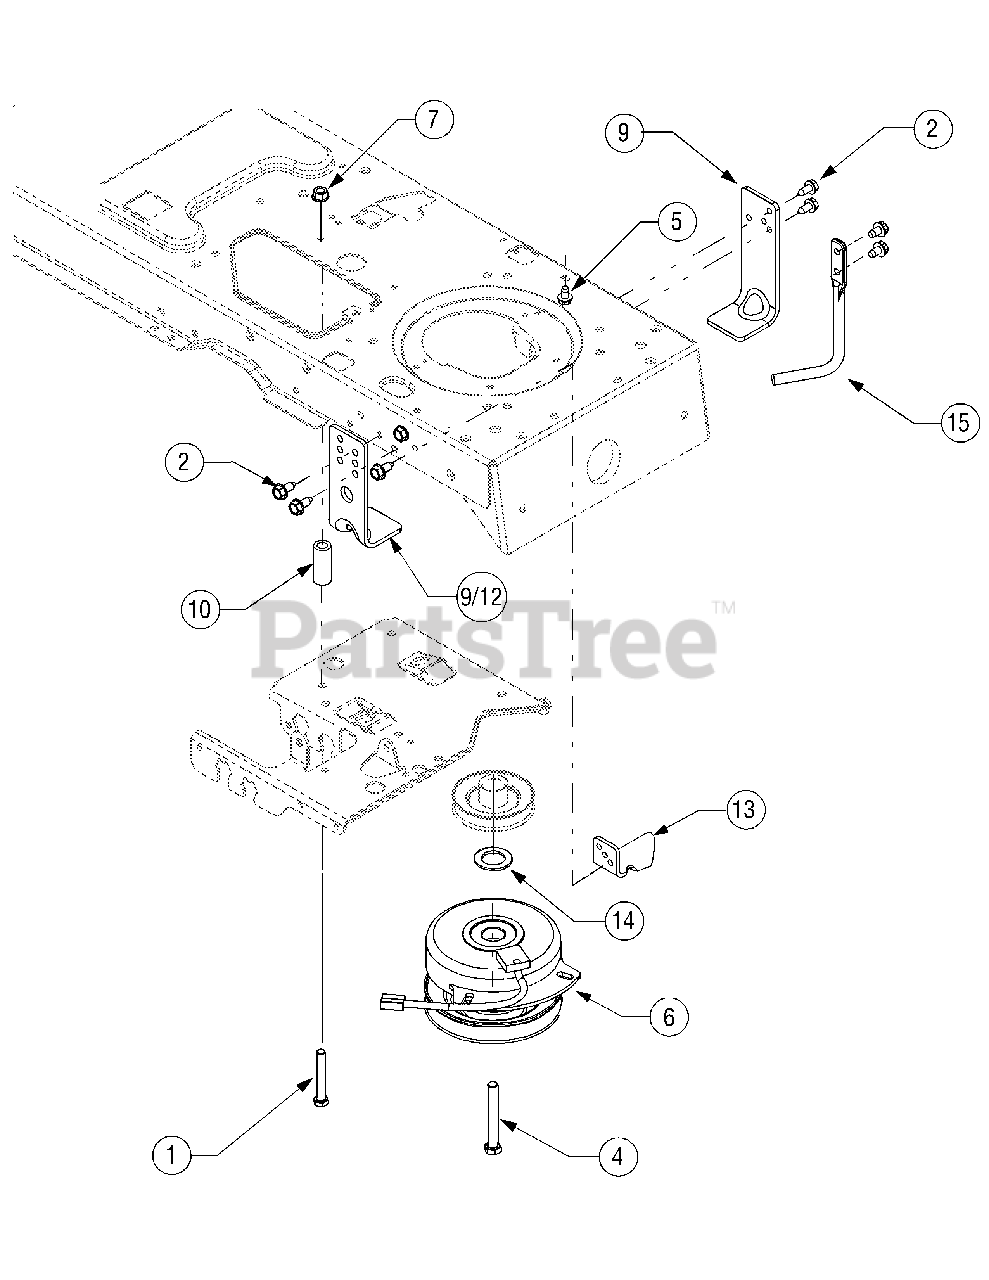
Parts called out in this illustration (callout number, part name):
1	Screw, 3/8-16 x 2.5 GR5
2	Screw, 5/16-12, .75
3	Screw, 5/16-18, .75
4	Screw, Hex Cap, 7/16-20 x 3.25 GR5
5	Screw, Hex, 5/16-18 x .5 (Model SLT 1550)
6	Clutch, PTO (Model SLT 1550)
6	Clutch, PTO (Model SLT 1554)
7	Nut, Hex. Nylon Lock, 3/8-16
8	Washer, Lock, 7/16, Regular Duty
11	Washer, Flat, 1.031 x 1.62 x .095
14	Washer, Flat, 1.031 x 1.62 x .095
15	Deck Stop Rod (Model SLT 1554)
